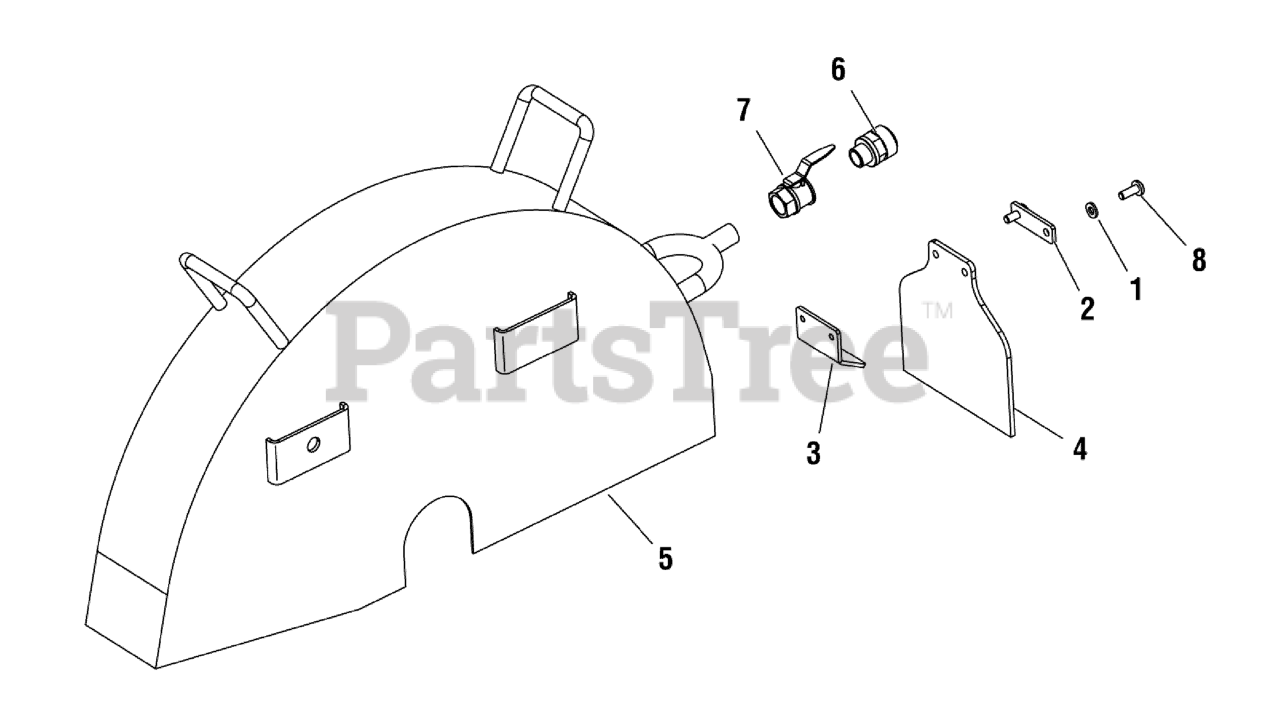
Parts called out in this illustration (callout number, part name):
1	WASHER, Flat
2	PLATE, Rubber, Outer
3	PLATE, Rubber, Inner
4	FENDER, Rubber
5	COVER, Blade
6	QUICK CONNECTOR, Female Joint
7	BALL VALVE, Brass
8	SCREW, Pan Head, Slotted, M6 x 16
